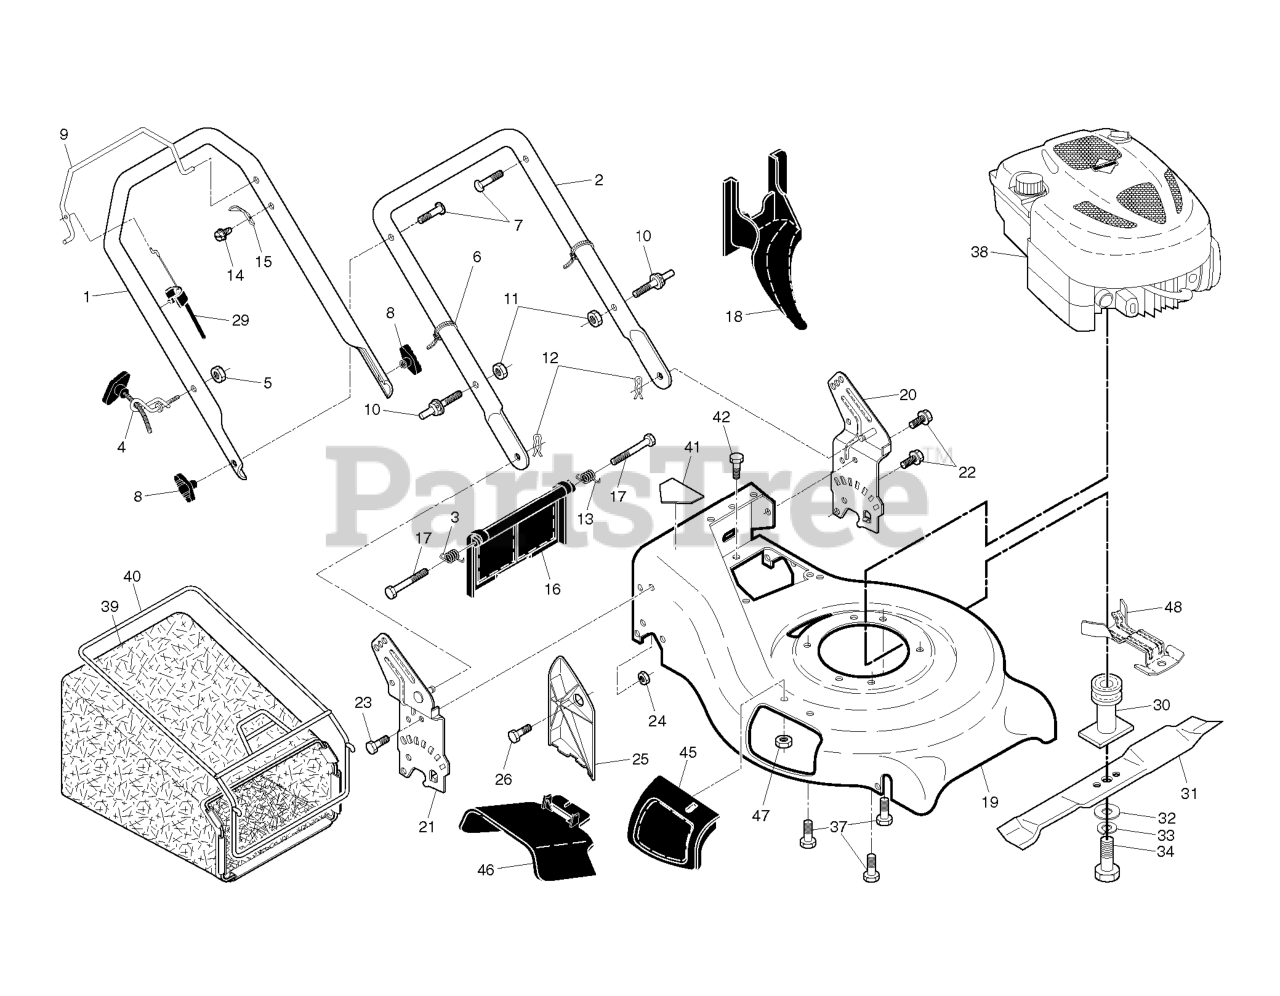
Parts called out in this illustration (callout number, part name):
1	UPPER HANDLE
2	HANDLE LOWER
3	SPRING.RH.REAR.DOOR.21.RWGD
4	RB GUIDE.ROPE.STD.BLK.ZIN WSL
5	NUT
6	TIE GUIDE
7	BOLT, HANDLE 5/16-18X1.75
8	KNOB, DEFLECTOR
11	NUT.LOCK.5/16-18
12	HAIRPIN COTTER
13	SPRING.LH.REAR.DOOR.21.RWGD
15	BRACKET UPSTOP
16	REAR DOOR ASSEMBLY
18	PLUG.MULCHER.RGD.21.
19	KIT.HSG.21.RGD.MC.SPT.BLK.CE
20	BRKT.ASM.HNDL.21.RWGD.LT
21	BRKT.ASM.HNDL
22	BOLT.HEX.HD.WASHER.5/16-18X.75
23	BOLT, HEX HEAD 5/16-18
24	NUT.71038.31-18.HEX.NYLOCK
25	CLIPPING DEFLECTOR
29	SNAP-ON.ZONE.CABLE.ASS
30	ADAPTER.BLADE/PULLEY.25M
31	BLADE.21.PUSH
32	WASHER,HARDEN
33	LOCKWASHER
34	SCREW, HEX HD 3/8-24 X 1-3/8
37	BOLT 3/8-16X1-1/8
40	FRAME.GBAG.21.RWGD.SC
41	DECAL.INTERNATIONL.CUTFINGER
42	SCREW 14-20 X 5/8
45	DOOR .ASM. MUCH
46	DASH.STEALTH.C.AM/HM
48	BRACKET.ENG/BELTKEEPER.BZP
